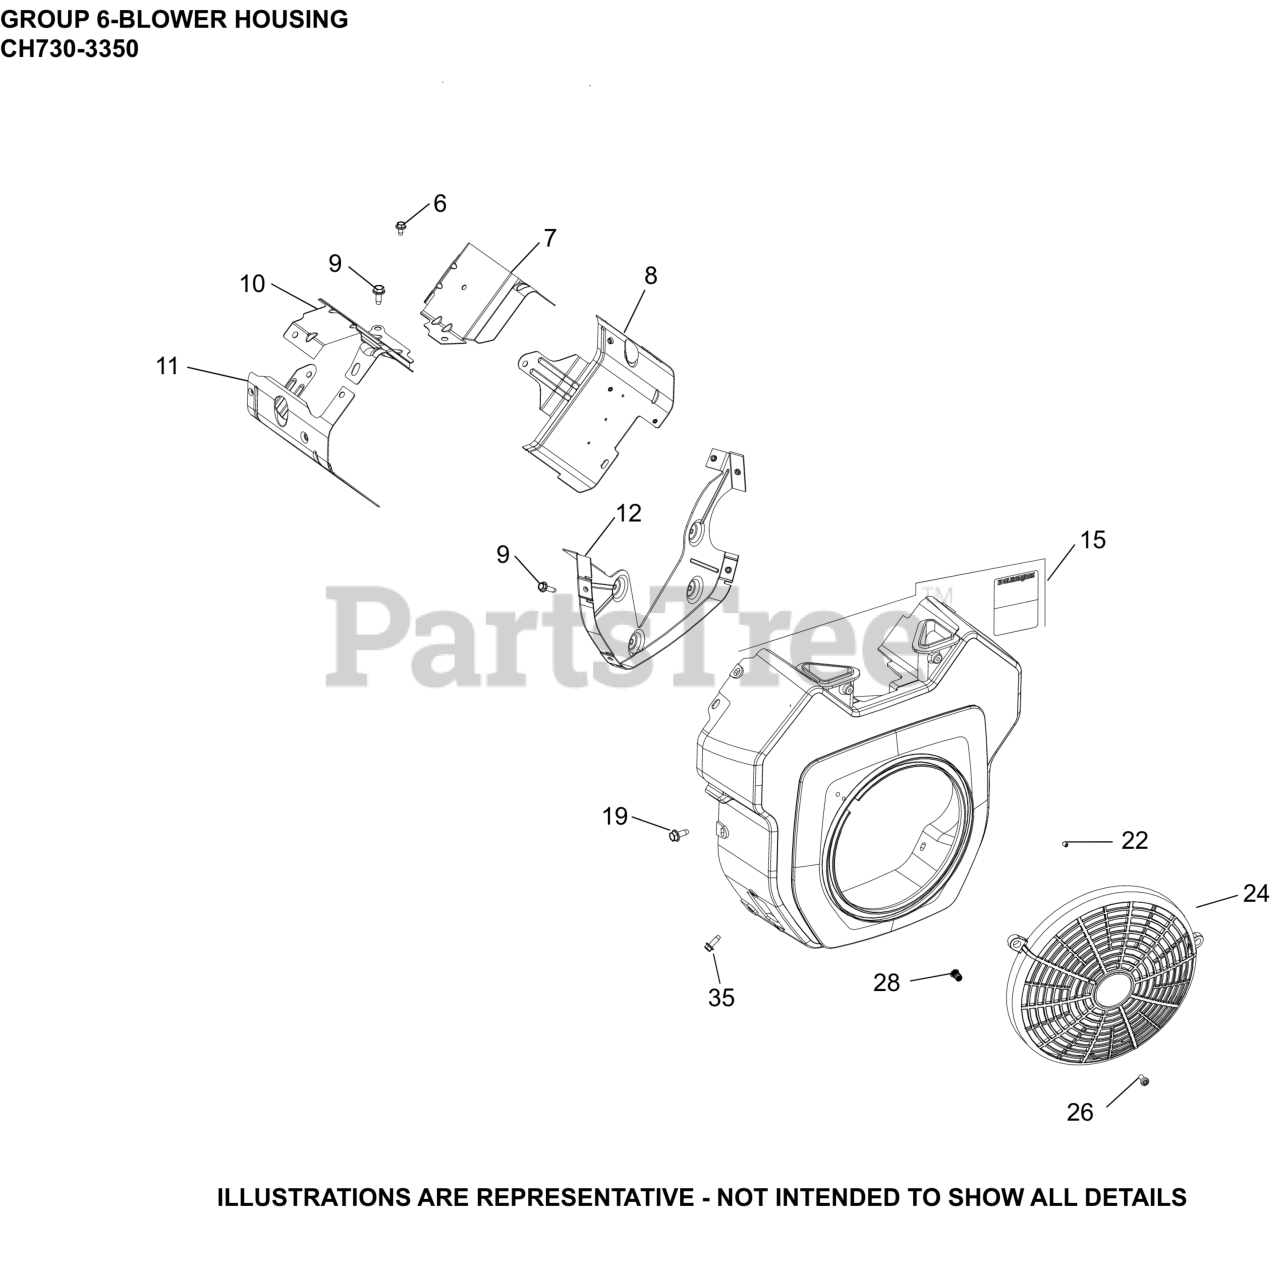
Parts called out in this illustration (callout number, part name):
6	SCREW, THREAD FORMING
7	BAFFLE, VALLEY #1 CYLINDER
8	KIT, CYL BAFFEL #1 SIDE
9	SCREW, THREAD FORMING
10	BAFFLE, VALLEY #2 CYLINDER
11	BAFFLE, LEFT BARREL
12	KIT, BACKING PLATE
15	HOUSING, BLOWER
15	KIT, BLOWER HOUSING
19	SCREW, THREAD FORMING
22	SCREW, THREAD FORMING
24	KIT, FIXED GUARD
26	SCREW, SEMS
28	INSERT, THREADED (M5)
35	SCREW, THREAD FORMING
